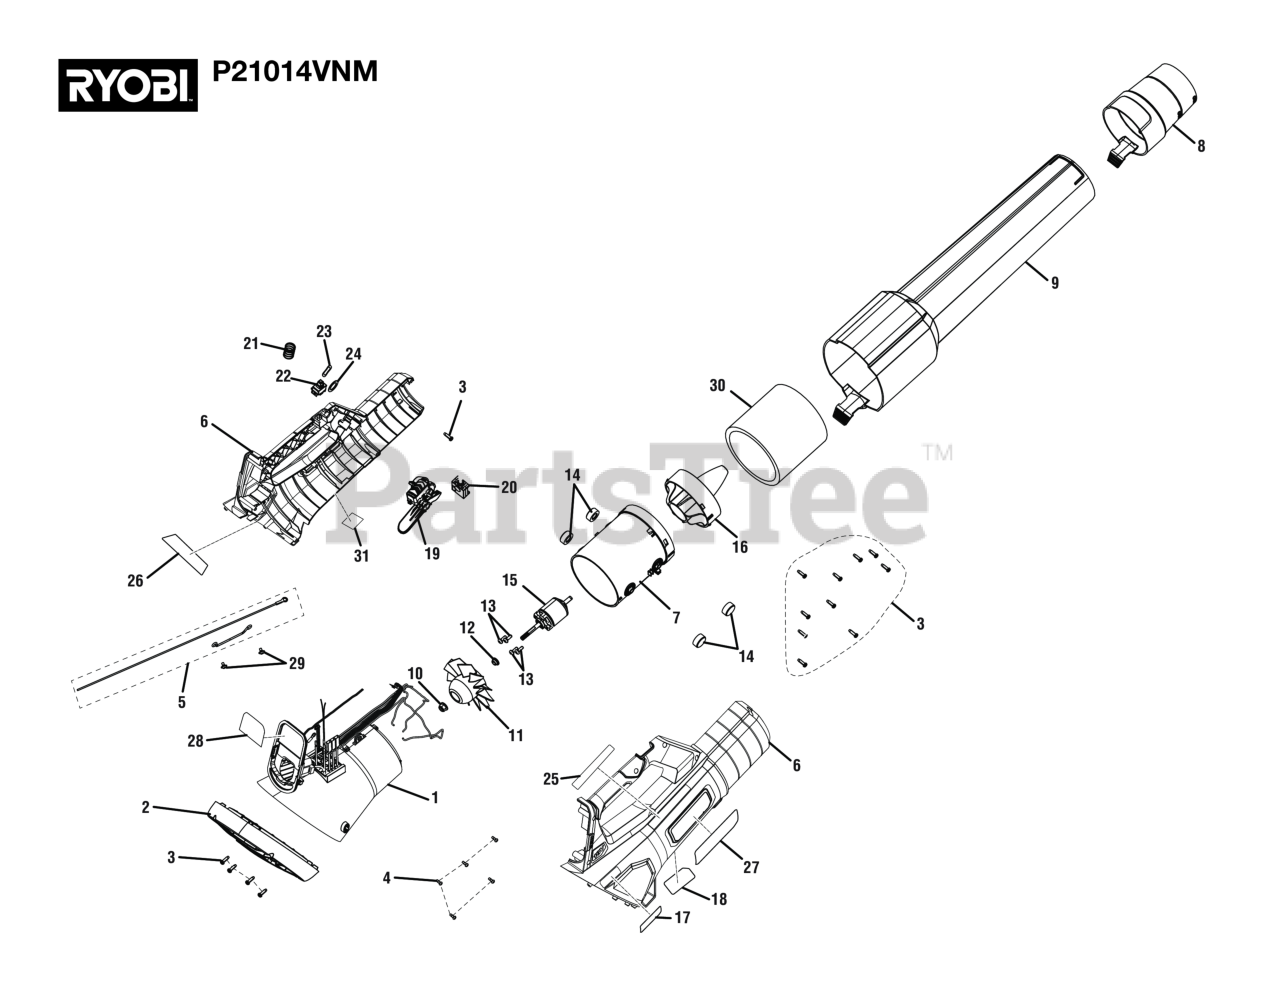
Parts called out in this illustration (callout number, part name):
1	Motor Controller and Inlet Bell Assembly (Inc. Key No. 28)
2	Inlet Guard
3	Screw (M4 x 14 mm, T15 Torx Pan Hd.))
4	Screw (M3 x 8 mm, Pan Hd., Pan Hd)
5	Grounding Strap Assembly
6	Housing Assembly (Inc. Key Nos. 17-18 & 25-27)
7	Stator Assembly
8	Speed Nozzle Assembly
9	Blower Tube Assembly
10	Flange Lock Nut (M6 x 1 mm)
13	Screw w/Tooth Washer (M4 x 12 mm, Pan Hd.)
14	Rubber Cap
16	Nose Cone
17	Ingestion Icon Label
19	Trigger and Cruise Control Assembly
20	Signal Switch
22	Push Switch
23	Wave Washer
24	Washer (OD21 x 14 x 1t)
25	Icon Label
26	WHISPER SERIES Logo Label
27	Warning Label
28	Data Label
29	Screw (M3 x 5 mm)
